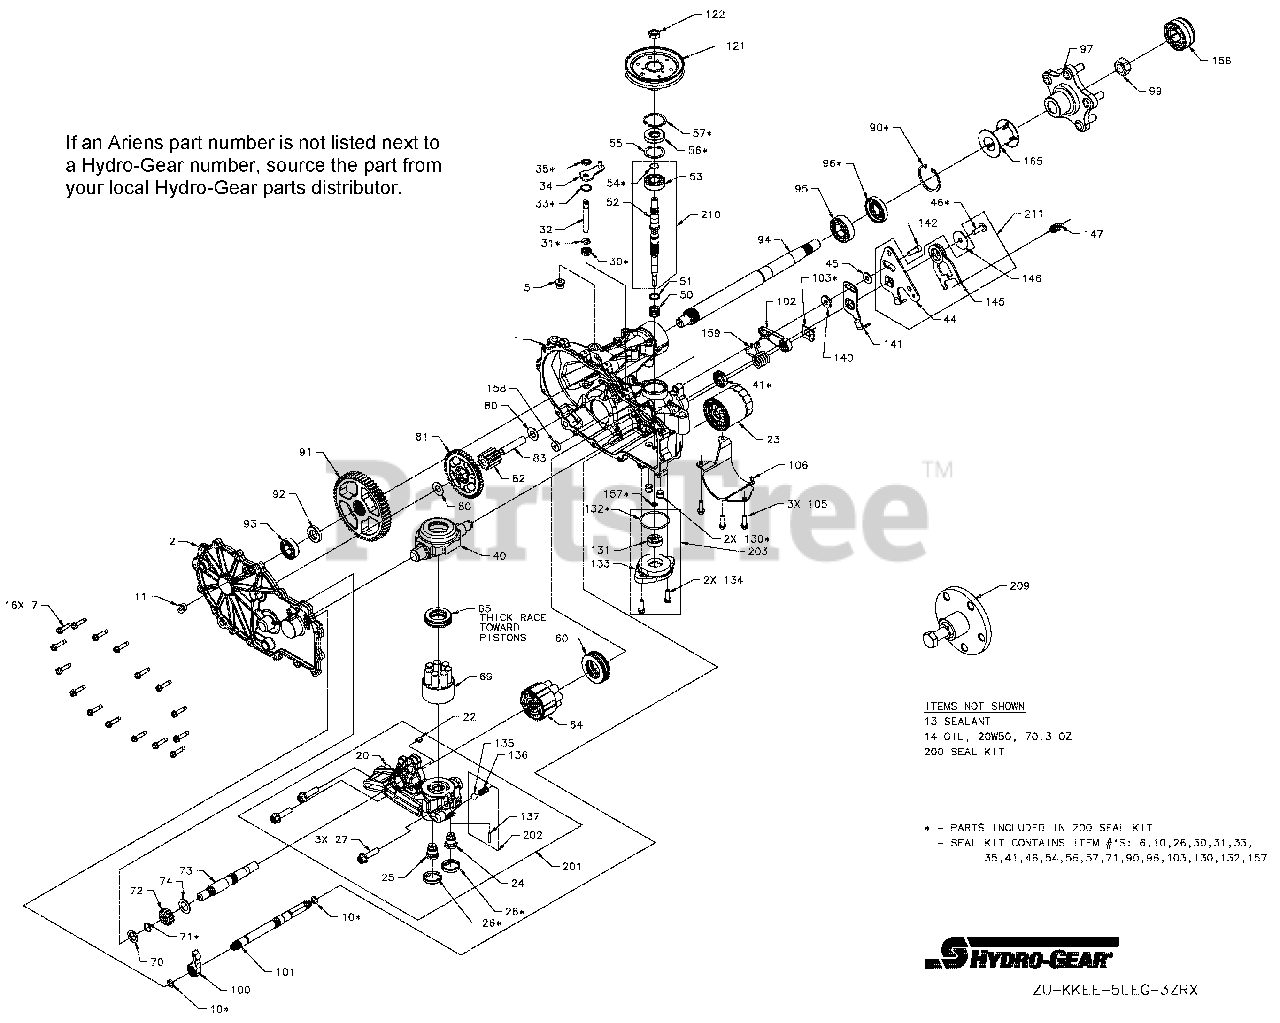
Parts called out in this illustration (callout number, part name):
7	HFHCS 1/4-20 x 1.125"
13	SEALANT
22	PLATE, BYPASS
23	FILTER, OIL
26	SEAL, PLUG 1.250 x .250
30	SEAL, LIP .375 x .75 x .25
31	RING, RET .375 EXTRNL
33	RING, RET .750 INTRNL
34	ARM, BYPASS
35	RING, RTNG .375 EXT
40	TRUNNION, SWASHPLATE
41	SEAL, LIP 12 x 32 x 7
45	WASHER .34 x .88 x .06
46	TWHCS 5/16-24 x 1.00 (PATCH)
50	SPRING, BLOCK
51	WASHER-FLAT .59 x .79 x .04
55	WASHER 1.23 x 1.56 x .04
56	SEAL, LIP 17 x 40 x 7
57	RING, RETAINING
60	BEARING, THRUST
64	ASS'Y, CYLINDER BLOCK, 16cc
65	BRG, THRUST PLASTIC CAGE
69	ASS'Y, BLOCK 7 PISTON
70	WASHER .63 x 1.0 x .05
71	RING, RETAINING_.625
74	WASHER .72 x 1.16 x .04
80	WASHER .5 x 1.0 x .03
83	JACK SHAFT (PIN)
90	RING, RET 2.06 INT
95	BRG, BALL 25.4 x 52 x 15
96	SEAL, LIP 1.000 x 2.049 x .375
97	KIT, HUB, 5 BOLT
99	NUT, HEX LOCK 3/4-16
103	CLIP, RETAINING
106	GUARD, FILTER, LH
121	PULLEY, 4.5 x 1.625
122	NUT,HEX JAM 1/2-20 W/ PATCH
131	GEROTOR ASSEMBLY (1.9 cc/rev)
132	O-RING, -137, 0.103 x 2.050
140	SPACER .320 x 1.005 x .179
141	ARM, NEUTRAL LEFT
142	SHCS 5/16-24 x 1 PATCH
146	WASHER, .343 x 1.500 x .062
147	SPRING, EXTNSN RTN-34LBS
158	MAGNET, RING
200	KIT, SEAL
201	KIT, CENTER SECTION, LH, CHRG
203	KIT, CHARGE PUMP
210	KIT, INPUT SHAFT
211	KIT, RTN, CCW
